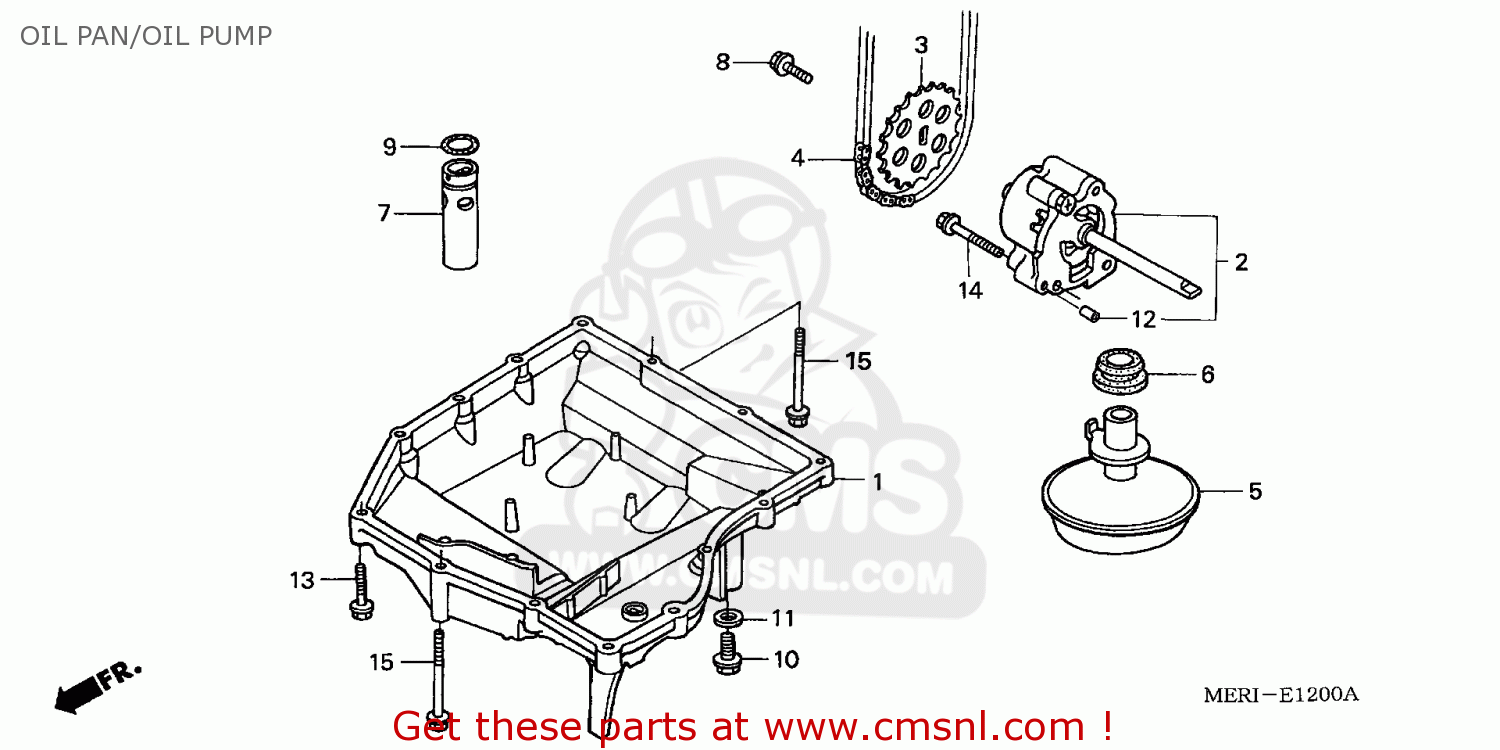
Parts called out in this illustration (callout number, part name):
1	OIL PAN
2	PUMP ASSY,OIL
3	SPROCKET,OIL PUMP
4	CHAIN,OIL PUMP (2
5	STRAINER COMP,OIL
6	PACKING,OIL STRAI (NAS)
7	VALVE ASSY.,RELIE
8	BOLT-WASHER,6X12
9	O-RING,14.8X2.2
10	BOLT DRAIN 12MM
12	DOWEL,PIN,8X10
13	BOLT,FLANGE,6X28
14	BOLT,FLANGE,6X40
15	BOLT,FLANGE,6X50
